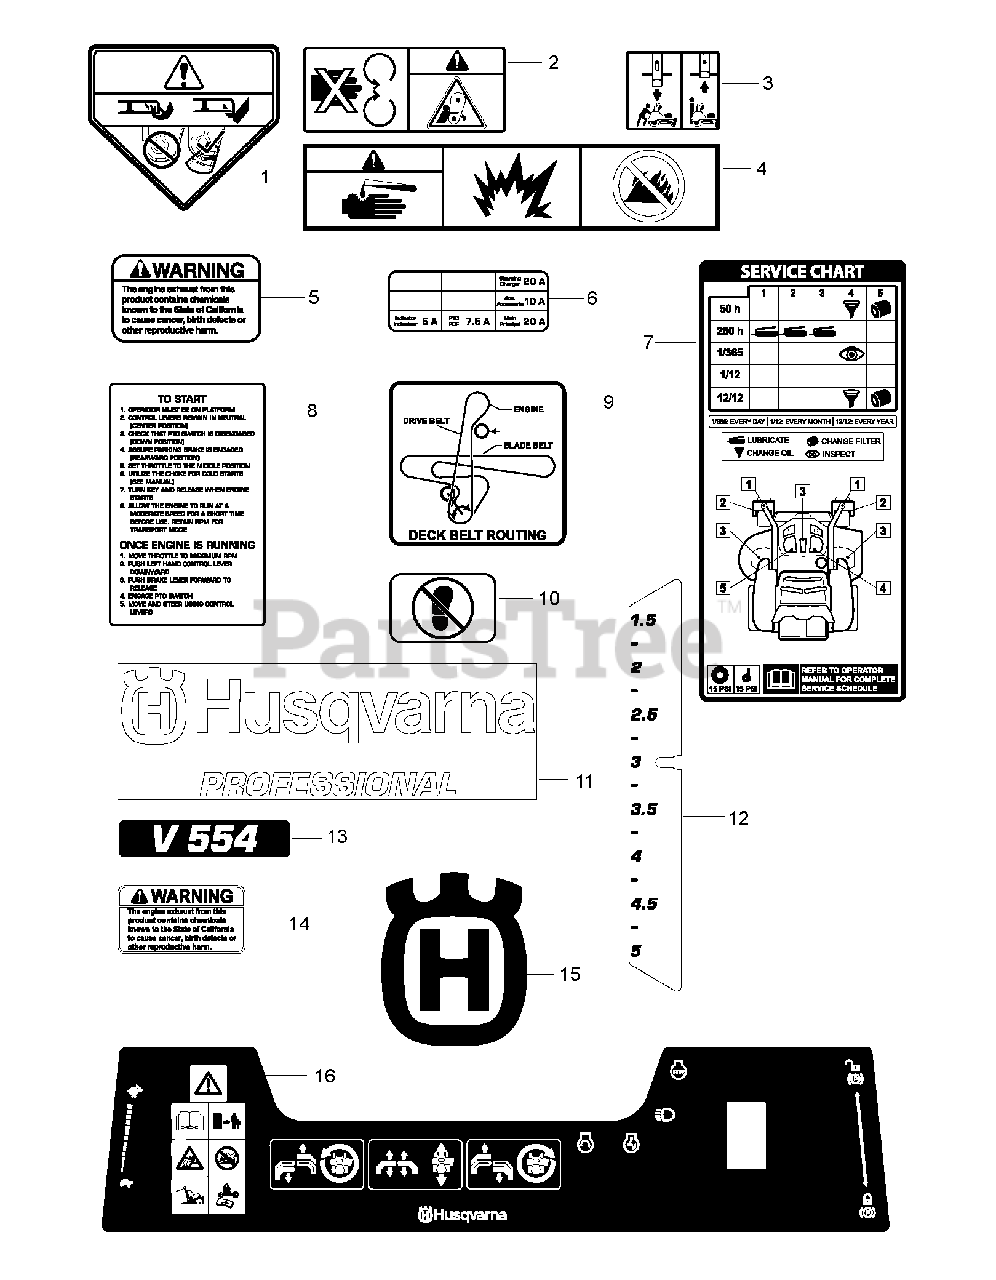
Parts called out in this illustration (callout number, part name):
1	DECAL, DECK DEFLECTOR, WARNING
2	DECAL, BELT DRIVE
3	Decal, ZTR Instruction Graphic
4	EURO DECAL-BATTERY WARNIN6
5	DECAL.DECK.6MIL./DEF.SHLD.WARN
6	Decal, ZTR Instruction Graphic
7	Decal, ZTR Instruction Graphic
8	Decal, ZTR Instruction Graphic
9	DECAL BELT ROUTING DECAL DECAL
10	DECAL.DECK.6MIL.EURO.NOSTEP
11	Decal, ZTR Instruction Graphic
12	Decal, ZTR Instruction Graphic
13	Decal, ZTR Instruction Graphic
14	DECAL, PROP. 65
15	DECAL.BADGE.55MM.CROWNH.HUSQ
16	Decal, ZTR Instruction Graphic
